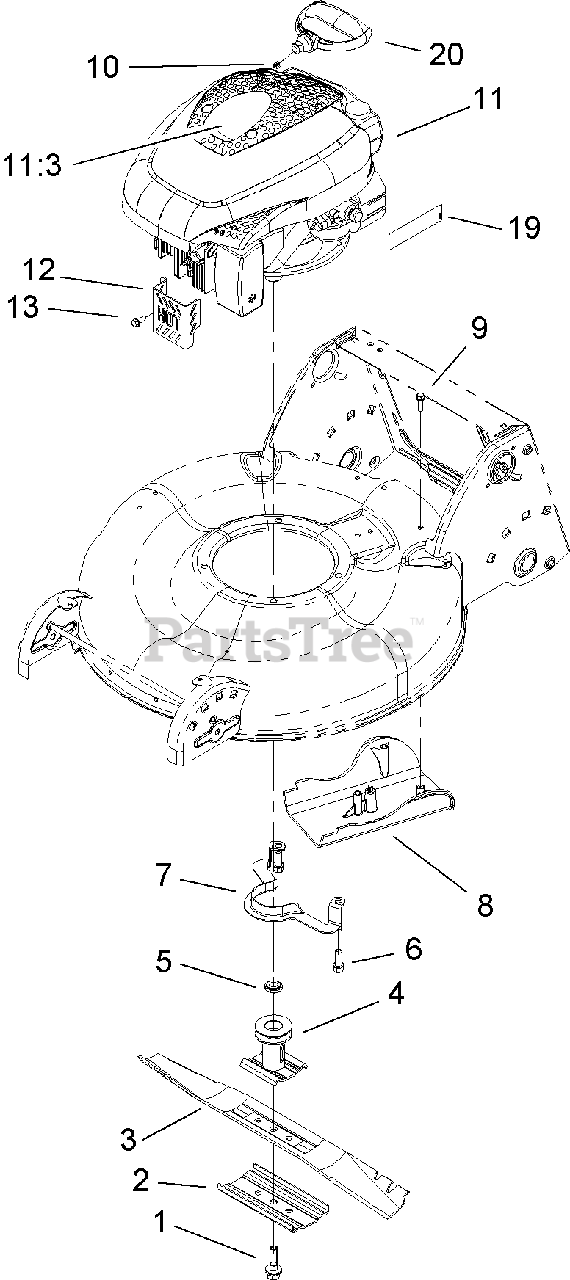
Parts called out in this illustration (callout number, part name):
1	BOLT-BLADE
2	SUPPORT-BLADE
3	BLADE-21 INCH
4	BLADE DRIVER ASM
5	Spacer-Driver
6	SCREW
8	COVER-BELT
9	SCREW-HWH
10	STOP-ROPE
11:3	DECAL-RECOIL
12	GUARD-MUFFLER
13	SCREW-HWH
19	DECAL-PRIMER
20	HANDLE-RECOIL
